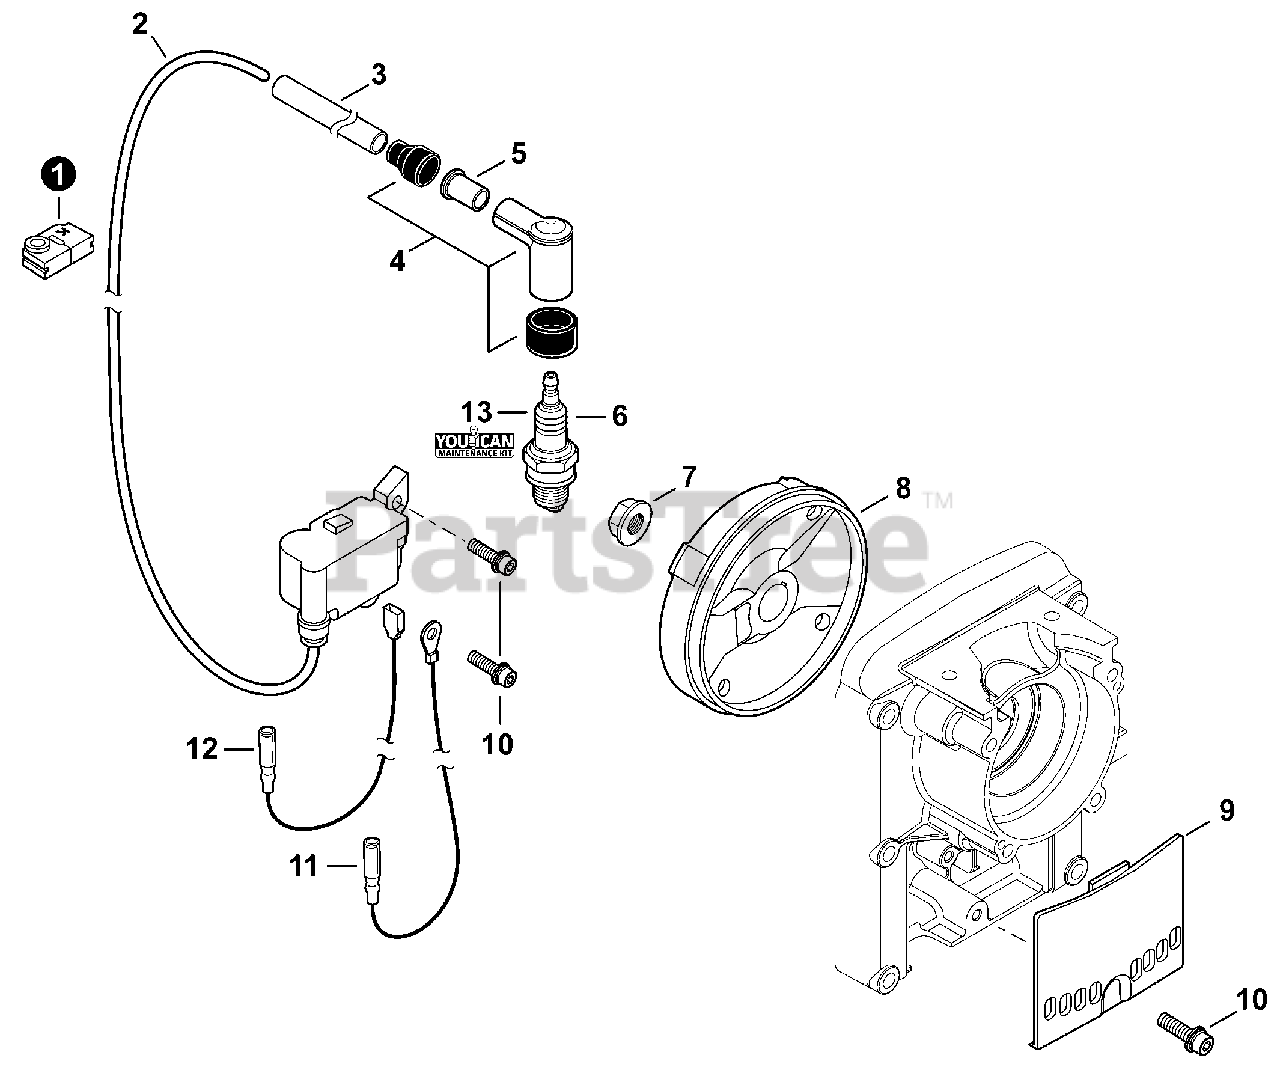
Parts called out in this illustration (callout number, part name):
1	GROMMET
2	COIL, IGNITION
3	TUBE, INSULATOR
4	CAP, SPARK PLUG
5	ADAPTOR, SPARK PLUG - CAP
6	SPARK PLUG - BPMR8Y
8	FLYWHEEL
9	COVER, DUST
10	BOLT M4×20
11	LEAD - GROUND
12	LEAD - IGNITION L= 170
13	TUNE-UP KIT - YOUCANT
